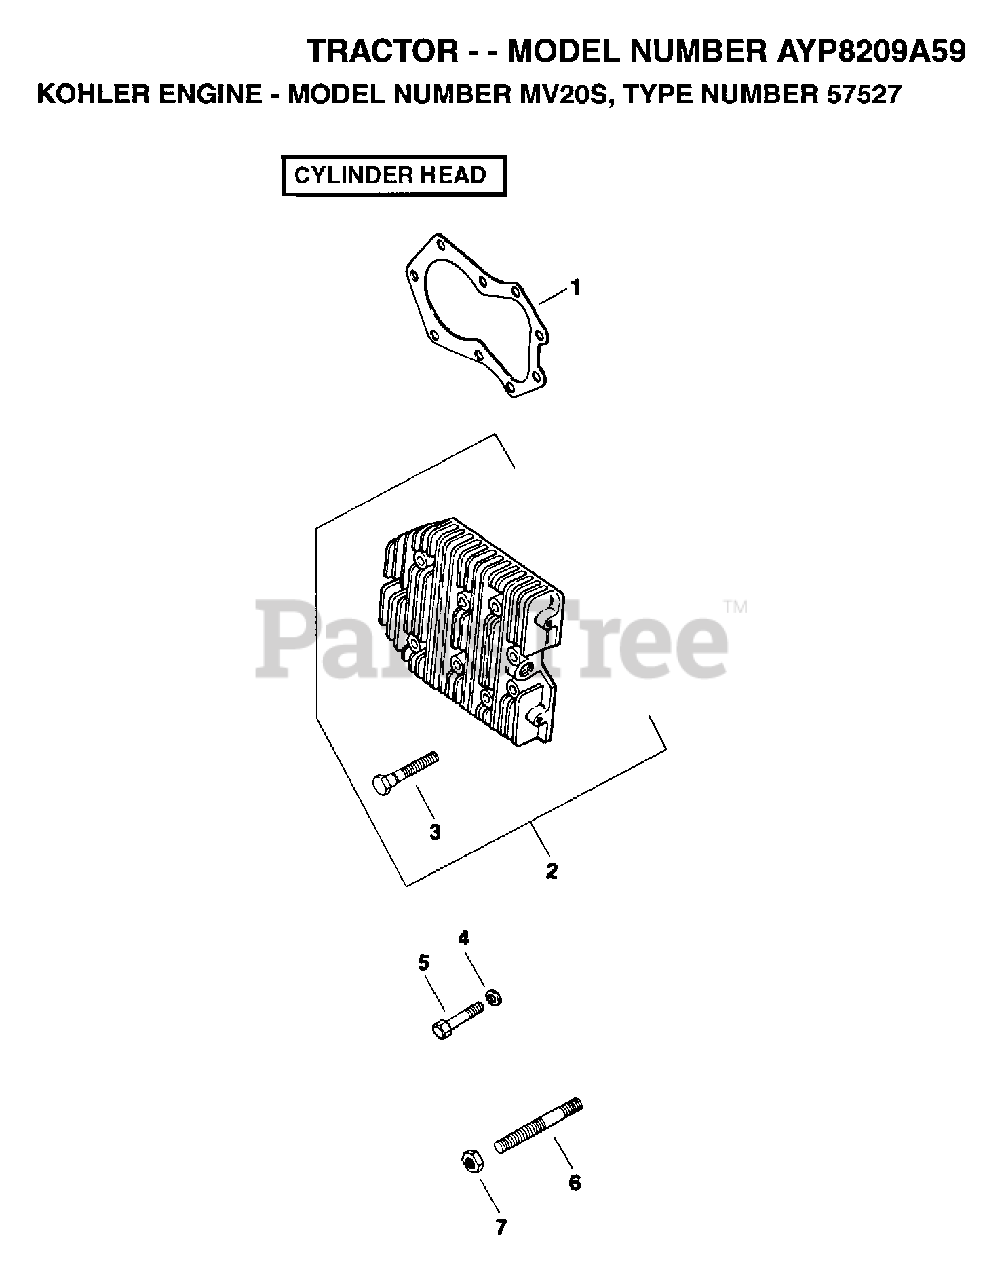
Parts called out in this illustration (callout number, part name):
2	KIT, CYL. HEAD
4	WASHER
7	NUT
